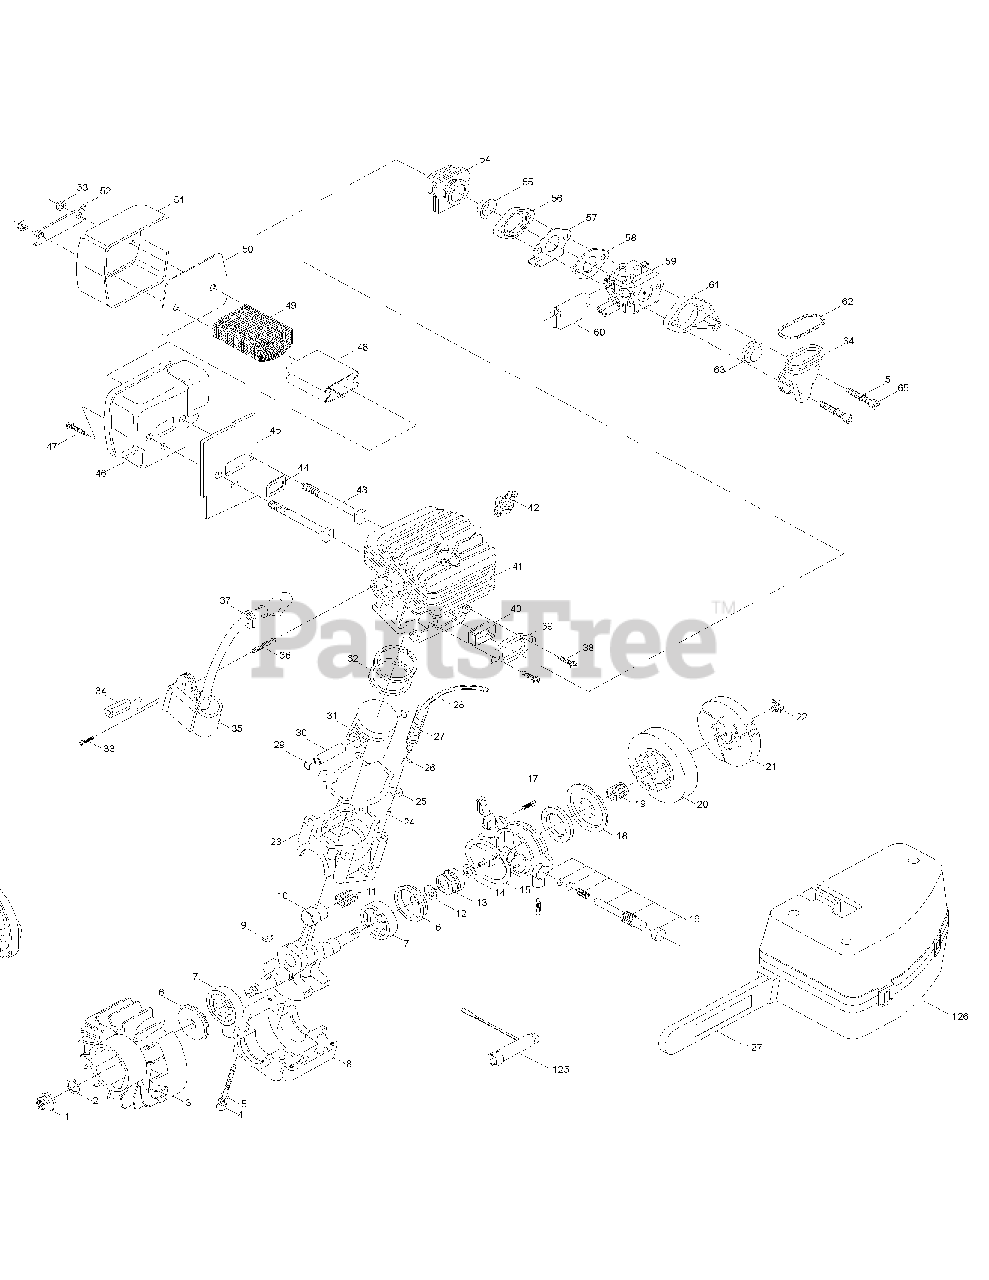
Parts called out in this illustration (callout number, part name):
3	FLYWHEEL
8	CRANKCASE LOWER
10	C'SHAFT/C'ROD ASS'Y
13	GEAR, WORM
16	PUMP ASS'Y
20	FRUM SPRKT ASS'Y
21	CLUTCH ASS'Y
23	CRANKCASE UPPER
24	FITTING, PULSE LINE
26	CLAMP, WIRE HOSE
27	CONDUIT, FLEX
32	RING, PISTON
35	IGNITION ASS'Y
38	SCREW
39	FLANGE
42	SPARK PLUG
46	MUFFLER BODY ASS'Y
51	COVER, MUFFLER
52	LOCKPLATE
54	BOOT, CARBURETOR
59	CARBURETOR
67	STARTER ASS'Y
74	PRIMER, REMOTE
76	CAP, FUEL
77	FILTER, FUEL
80	FUEL/OIL TANK ASS'Y
81	VALVE DUCKBILL
90	PLATE, BAR
91	PLATE, FLANGE
93	20" CHAIN
96	CHAIN BRAKE ASS'Y
99	CKOKE ASS'Y
100	ROD, CHOKE
102	ISOLATOR ASS'Y
103	CABLE ASS'Y
105	FRAME, REAR
107	RELEASE, TRIGGER
113	ISOLATOR ASS'Y
114	WIRE ASS'Y
115	COVER ASS'Y, HANDLE
119	HANDLE ASS'Y
120	COVER ASS'Y
123	AIR CLEANER ASS'Y
126	CARRY CASE
